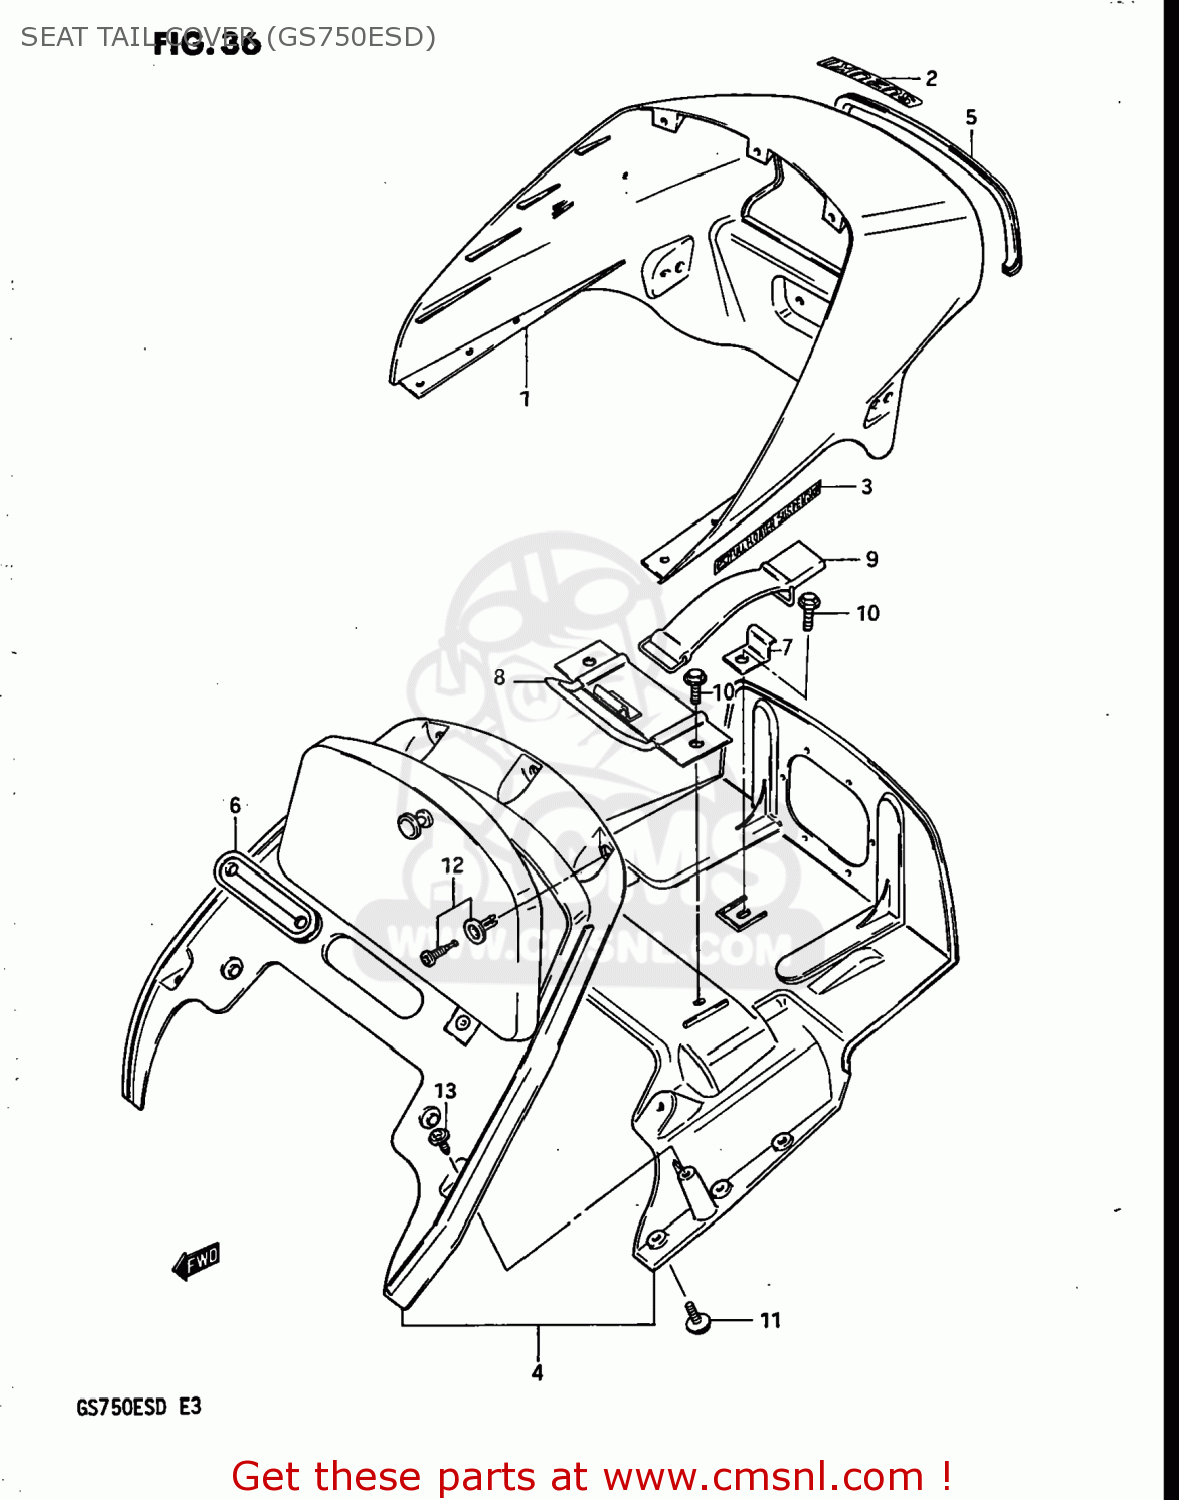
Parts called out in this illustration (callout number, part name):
1	COVER COMP,SEAT TAIL
2	EMBLEM
3	EMBLEM
4	FLAP,SEAT TAIL COVER
5	MOLDING,SEAT TAIL COVER
6	GROMMET,SEAT TAIL COVER
7	PLATE,CHAIN LOCK HOLDER
8	PLATE,SEAT HOOK
9	BAND
10	BOLT
11	SCREW
12	CLIP
13	SCREW
